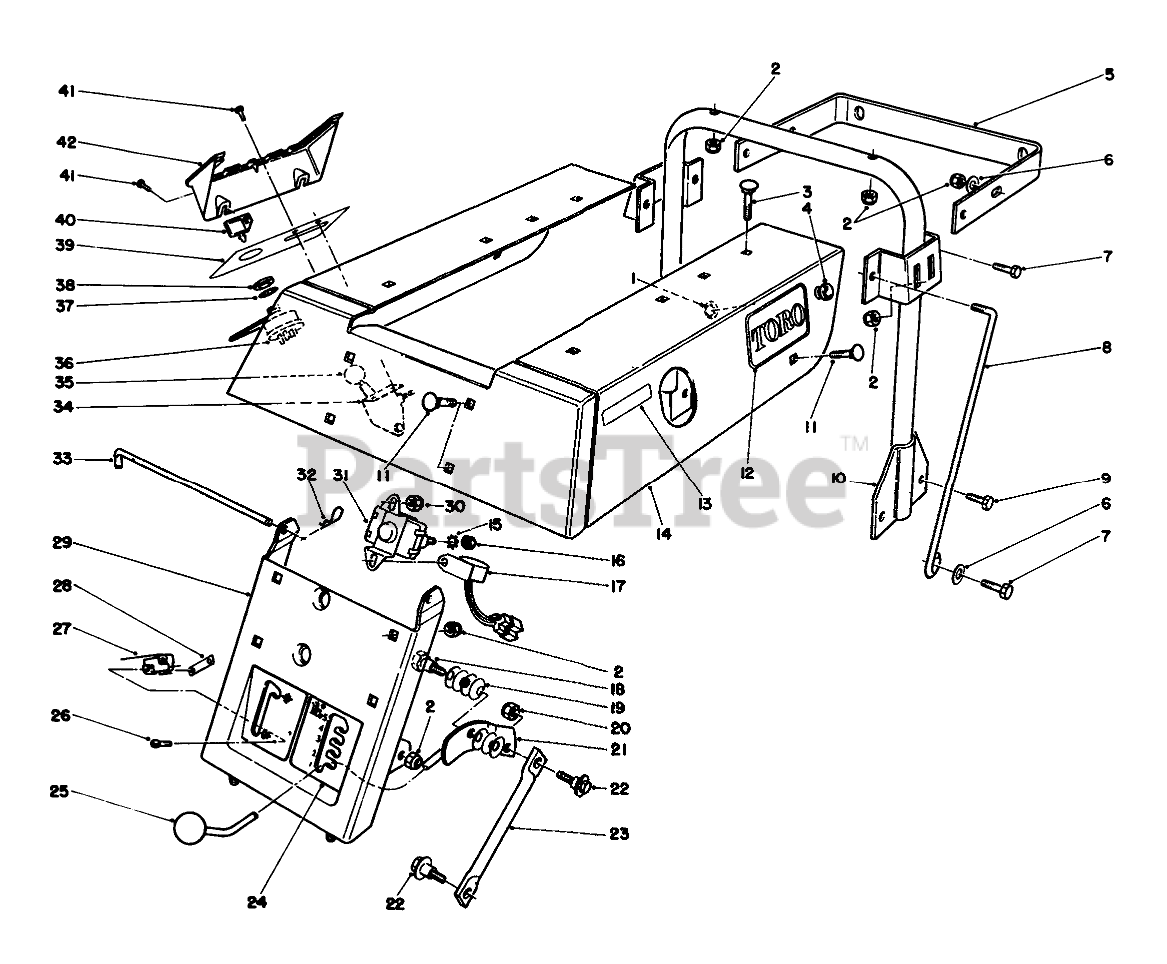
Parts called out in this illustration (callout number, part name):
1	PUSH NUT
2	NUT-LOCK, NI
3	SCREW-CARR
4	GUIDE-ROPE, STARTER
5	Standbar
6	WASHER-PLAIN
7	SCREW-HH
8	BRACE-SEAT SUPPORT
9	SCREW-HH
10	Seat Support W.A.
11	SCREW-CARR
12	DECAL
13	DECAL - CHECK OIL
14	Body W.A.-Rear
15	WASHER-LOCK/EXT
16	NUT-JAM
17	Module-Interlock
18	BOLT-SHOULDER
19	WASHER-BELLEVILLE
20	NUT-LOCK, NI
21	HOC HDLE WA
22	BOLT-SHOULDER
23	LINK-HOC
24	DECAL - HOC/DECK ENGAGE
25	KNOB-CONTROL
26	SCREW-SPH
27	SWITCH-MICRO
28	NUT-SPEED
29	Support W.A.-Seat
30	NUT-LOCK, NI
31	SOLENOID
32	PIN-COTTER
33	SEAT BASE ROD
34	CONTROL-THROTTLE
35	Knob
36	SWITCH-STARTER
37	Washer-Int. Tooth (Included with Ref. #36)
38	Nut-Hex (Included with Ref. #36)
39	DECAL - CONTROL PANEL
40	KEY-IGNITION
41	SCREW-THD FORM, HWH
42	COVER-CONTROL PLATE
